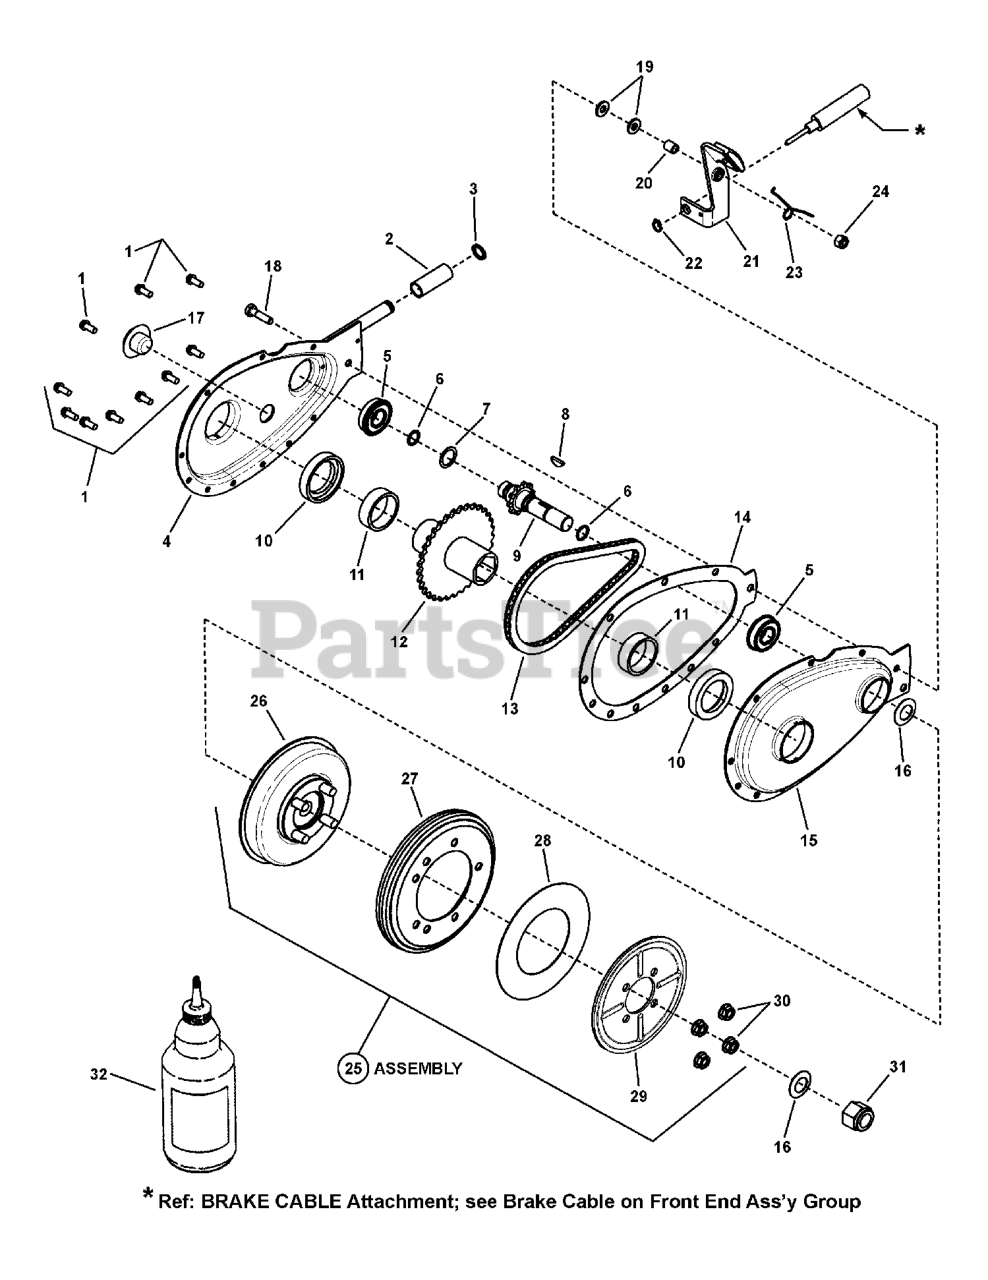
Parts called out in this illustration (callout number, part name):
1	SCREW, 10-24 x 1/2" Hex Washer Self-Tap
2	ROLLER, 1-3/8 Long
3	RING, 1/2" External Retaining (Heavy Duty)
4	WELDMENT, Primary Chain Case Half, Right Hand
5	BEARING, .625 x 1.37 x .435
6	O-RING, 1/2 x 5/8"
7	WASHER, Shim .625 x .875
8	KEY, #5 Woodruff
9	WELDMENT, Sprocket & Shaft
10	THRUST WASHER, Nylon
11	BEARING, Needle 1.355" ID x 1.6245" OD x .5" Wide
12	WELDMENT, Hub & Sprocket
13	CHAIN, 46 Pitch (#35 Endless)
14	GASKET, Primary Chain Case
15	PRIMARY CHAIN CASE HALF, Left Hand
16	WASHER, 5/8" Belleville
17	PLUG, 3/4" Cup Insert
18	SCREW, 1/4-28 x 1" Hex Head Cap, (Washer Face) GR 5
19	WASHER, .28 x .63 x .06 Flat, GR 5
20	SPACER, Brake Arm Pivot (.418/.403 long)
21	KIT, Brake Lever Assembly (Includes brake pad & rivet)
22	RING, 3/8" External Retaining
23	* SPRING, Torsional Brake Return
24	NUT, 1/4-28 Hex Top Lock
25	KIT, Smooth Clutch Assembly (non-asbestos)
26	KIT, Driven Disc Hub (assembly)
27	KIT, Driven Disc (rubber tire bonded to rim)
28	THRUST WASHER
29	PLATE, Drive Disc
30	NUT, 5/16-24 Hex Flange Lock
31	NUT, 5/8-18 Hex Nyloc
32	** GREASE, Transmission (Use 2 oz. Maximum)
